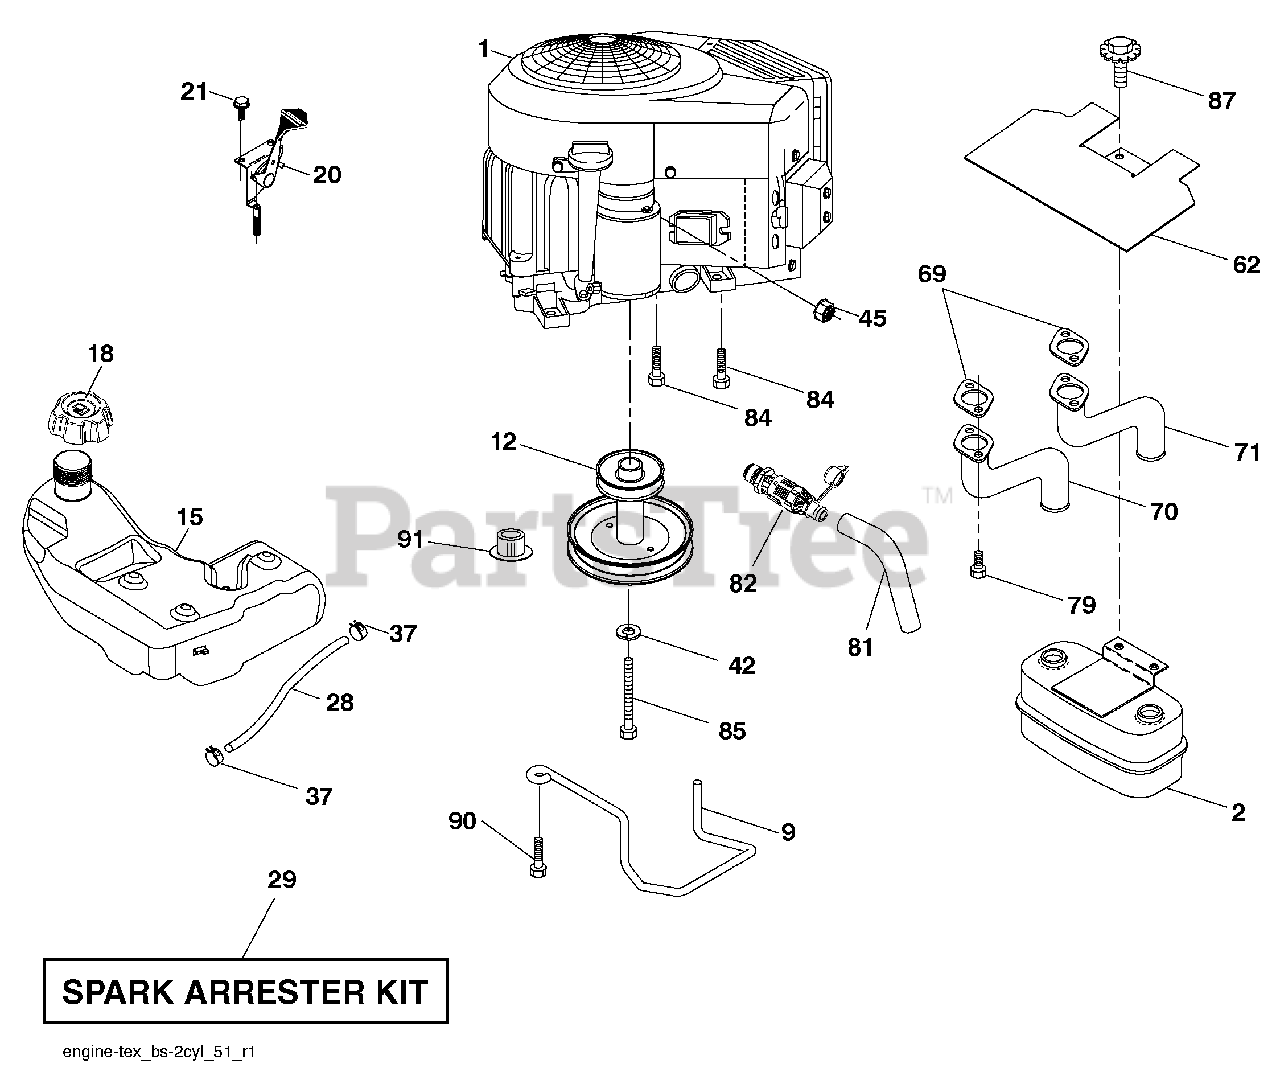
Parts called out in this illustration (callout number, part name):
2	Muffler
9	Keeper Belt Engine
12	Pulley Engine
15	Tank Fuel
18	Cap Fuel
20	Control Throttle/Choke
21	Screw #10 x 0.750 BOS Thread
28	Fuel Line
29	Spark Arrester Kit
37	Clamp Hose
42	Washer Lock 7/16
45	Nut Keps Hex 1/4-20 unc
62	Shield Heat Muffler
69	Gasket
70	Exhaust Tube LH
71	Exhaust Tube RH
79	Screw Socket HD 5/16-18 x 1
81	Tube Drain Oil Easy
82	Valve Drain Oil
84	Screw 3/8-16 x 1-1/4
85	Bolt 7/16-20 x 4 x Gr. 5-1.5
87	Bolt 5/16 - 18 x 3/4
90	Screw 3/8-16 x 1
91	Bushing
